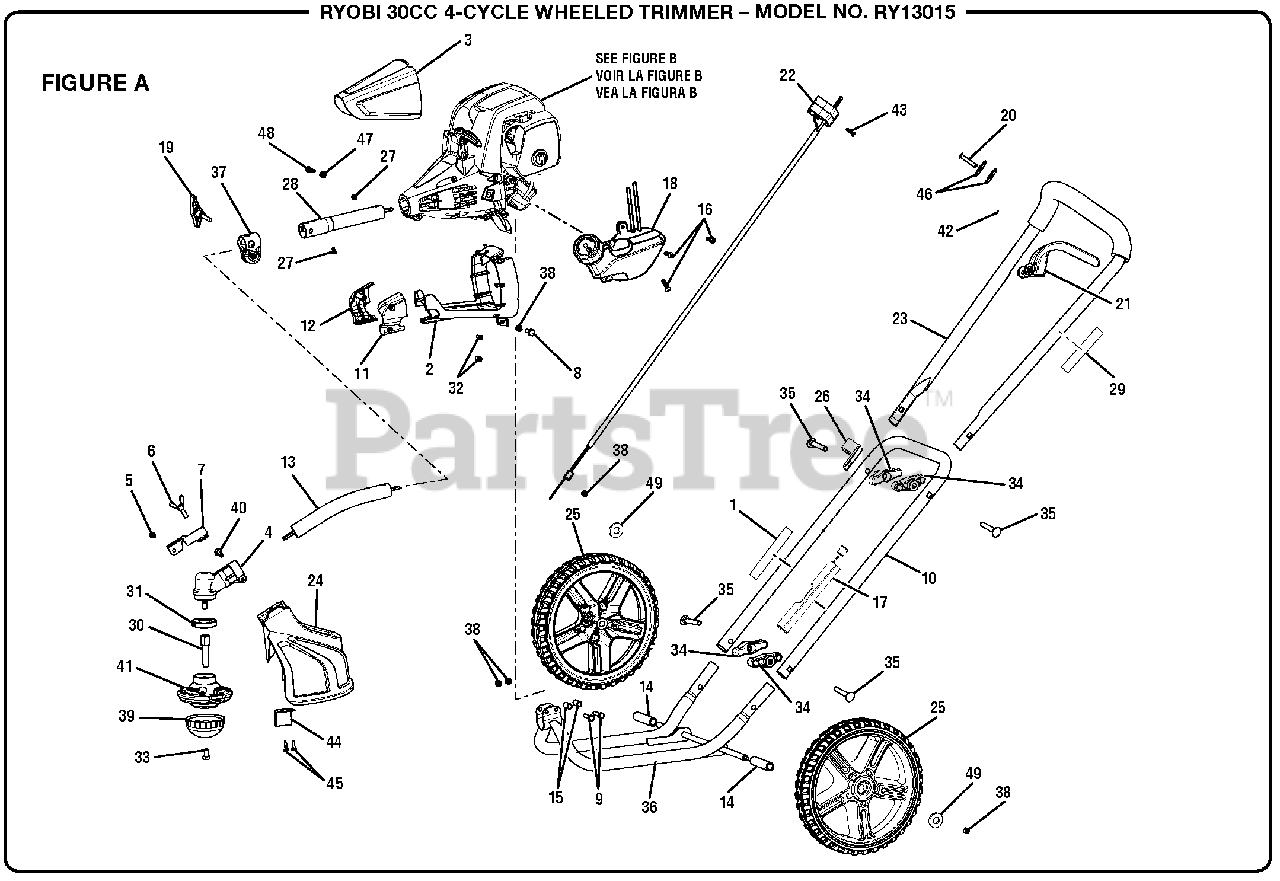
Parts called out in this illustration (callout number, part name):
1	Warning Label (Combustion)
2	Screen Frame
3	Mesh Screen
4	Gear Case Assembly
5	Screw (10-24 x 5/8 in., Hex Washer Hd.)
6	Wing Screw (1/4-20 x 3/4 in.)
7	String Guard Clamp
8	Bolt (M6 x 16 mm, Hex Hd.)
9	Bolt (M6 x 28 mm, Hex Hd.)
10	Center Handle
11	Left Screen Cap
12	Right Screen Cap
13	Lower Boom Assembly
14	Shaft Spacer
15	Clamp Spacer
16	Screw (M4)
17	Line Carrier Assembly
18	Fuel Tank & Cap Assembly
19	Knob (1/4-20)
20	Pivot Pin
22	Throttle Cable Assembly
23	Upper Handle Assembly
24	Grass Shield (Incl. Key Nos. 44-45)
25	10 in. Wheel Assembly
26	Cable Clip
27	Screw (8-16 x 5/16 in., Torx)
28	Upper Boom Assembly
29	Warning Label
30	Stringhead Adapter w/Shaft
31	Flanged Washer
32	Screw (M4 x 12 mm, T20)
33	Screw (5/16 x 1/2 in., Left Hand)
34	Knob w/Nut Assembly
35	Carriage Bolt
36	Frame Assembly
37	Split Boom Clamp
38	Lock Nut (M6)
40	Screw (1/4-20 x 1-1/4 in.)
41	Stringhead Assembly
44	Cut-off Blade
45	Screw (8-16 x 5/8 in.)
47	Hex Nut (M6)
48	Screw (M6 x 20 mm)
